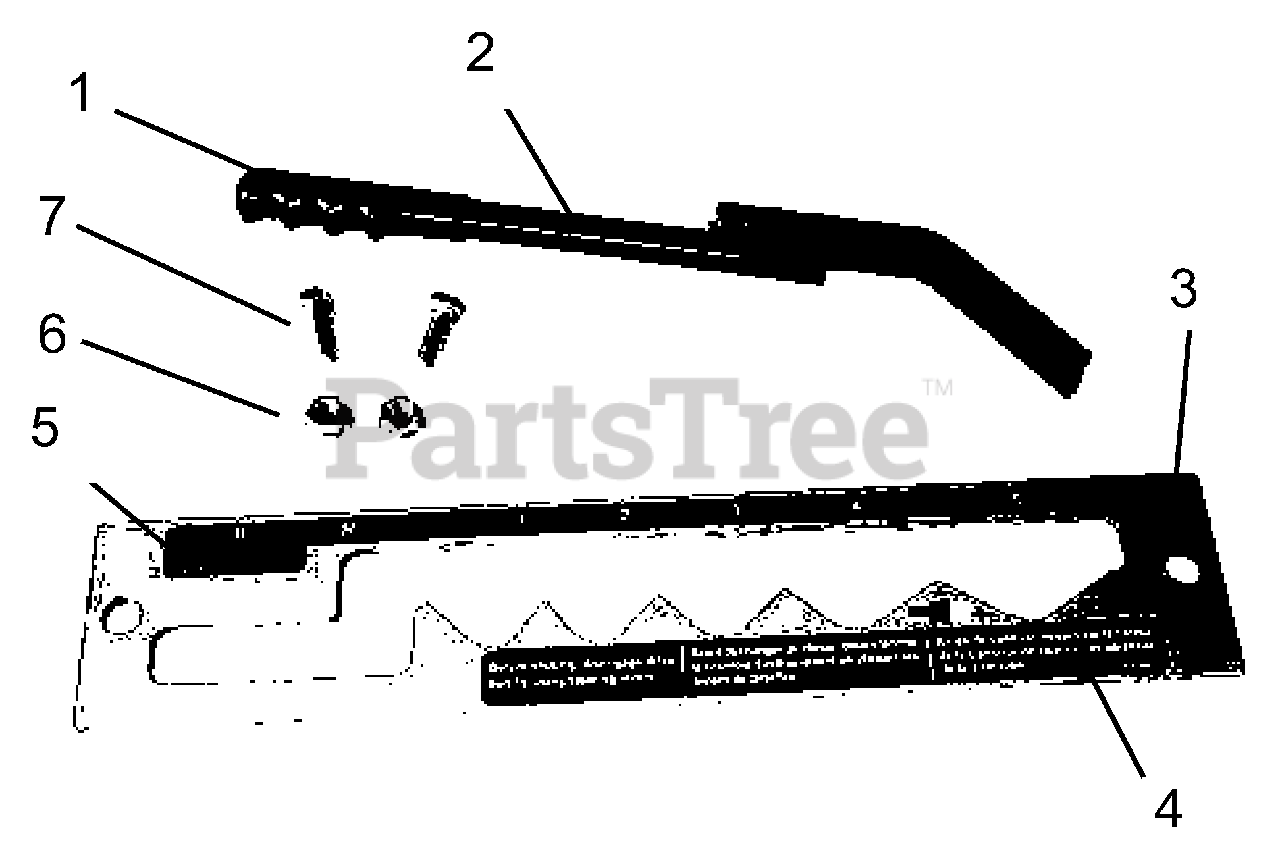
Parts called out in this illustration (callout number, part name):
1	Grip
2	Shift Lever
3	Shift Lever Detent Plate
4	Gear Declutch Decal
5	Shift Lever Decal
6	Nylon Locknut, 3/8-16
7	Hex Bolt, 3/8-16 x 1 Grade 5
